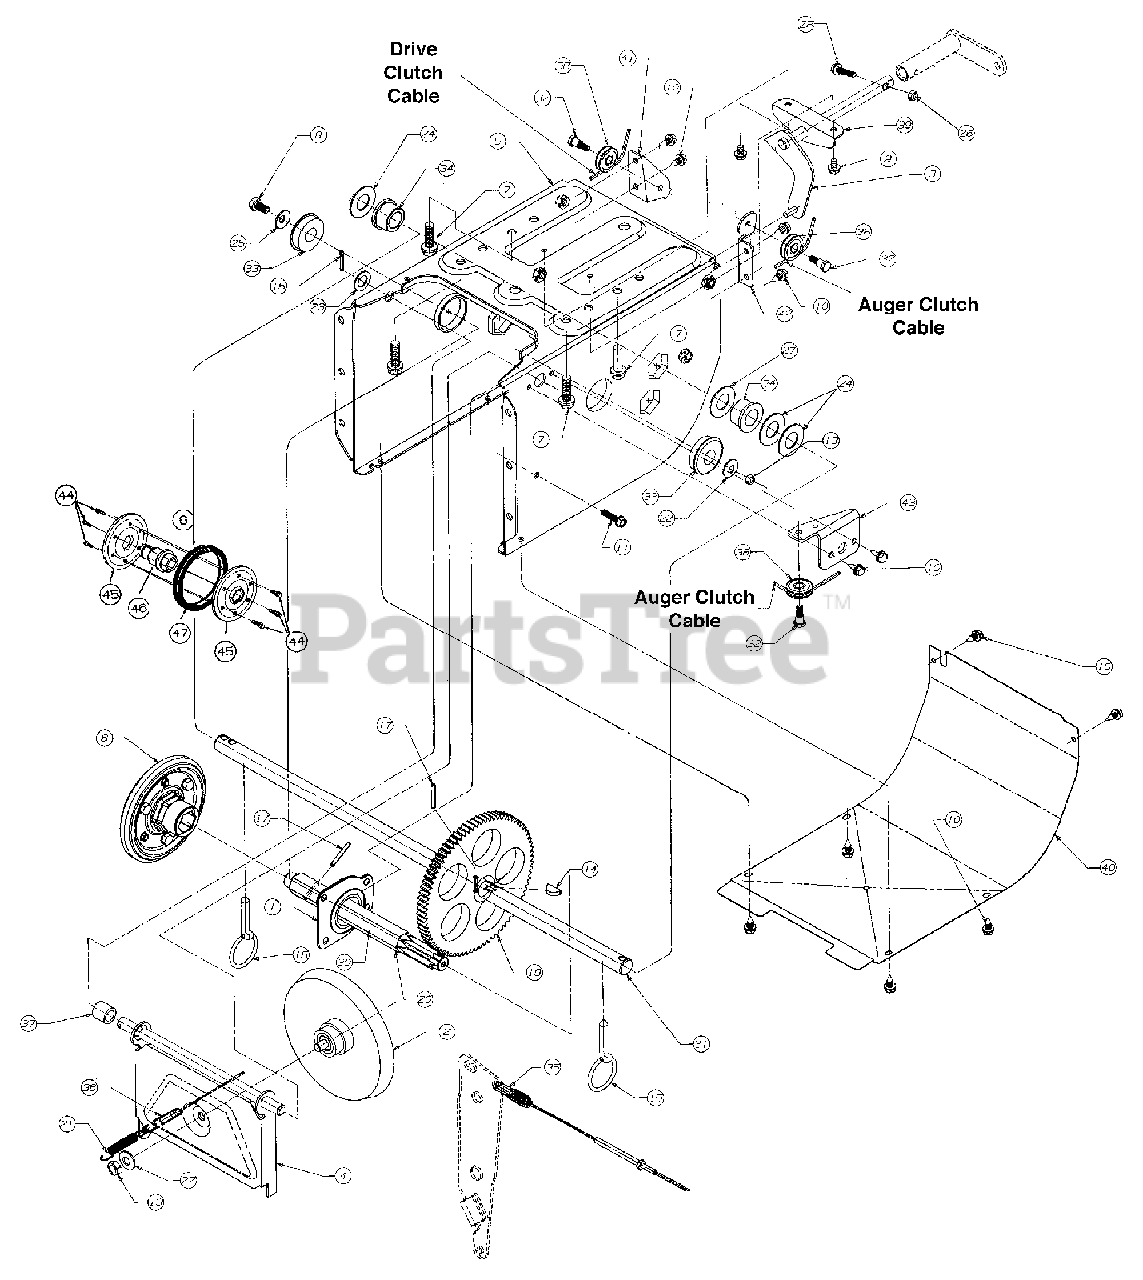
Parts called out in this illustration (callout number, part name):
1	Bearing Ass'y.
2	Ass'y., Friction Wheel Disc
3	Rod Shift, Wheel Drive
7	Hex Self-Tap Screw
8	Hex Hd. Cap Screw
9	Scr., Hex Wash. Hd.
10	Hex Self-Tap Scr.
11	Screw, Hex
13	Nut, Hex
15	Pin, Klick
16	Pin, Cotter
17	Pin, Roll
20	Shaft, Hex
21	Extension Spring
22	Washer, Bell
23	Flat Washer
24	Washer, Flat
25	Washer, Bell
27	Flat Washer
28	Screw
31	Axle .750 x 22.2
31	Axle .750 x 24.5
32	Screw, Shoulder
33	Bearing, Ball
34	Flange Bearing
35	Cable, Auger
36	Cable, Clutch
37	Spacer
38	Roller, Cable
45	Friction Plate
46	Friction Wheel Hub
47	Friction Wheel Rubber
